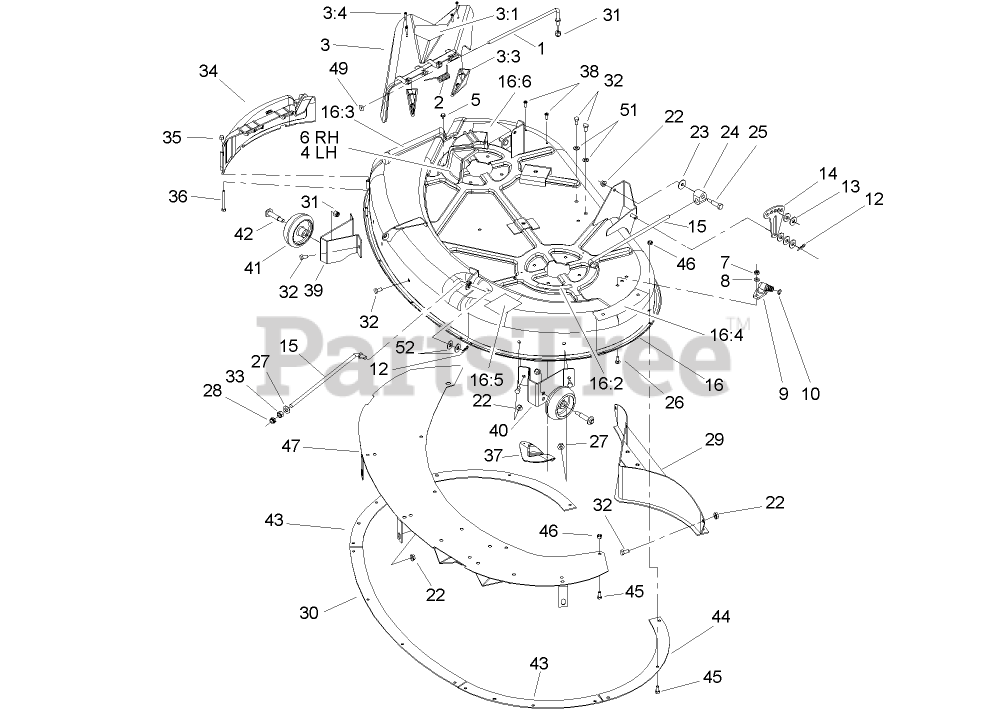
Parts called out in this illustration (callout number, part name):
1	ROD-PIVOT
2	SPRING
3	DEFLECTOR ASM
3:1	DECAL-DANGER
3:3	KICKER
3:4	SCREW-PPH
5	SCREW-HWHTF
6	GUIDE-BELT, RH
7	NUT-LOCK, NI
8	WASHER-FLAT
10	O-RING
12	PIN-HAIR
13	WASHER-HARDENED
14	LINK-ADJUSTING, HOC
15	ROD-HANGER
16:2	DECAL-DANGER, SHIELD
16:3	DECAL-DANGER, DEFLECTOR
16:4	DECAL-DANGER
16:5	DECAL-ROUTING, BELT
16:6	DECAL-DANGER
22	NUT-HF
23	WASHER-PIVOT
24	TRUNNION-HOC
25	SCREW-SHOULDER, HH
26	BOLT-CARR
27	WASHER-FLAT
28	NUT-LOCK, NI
29	REAR BAFFLE ASM
30	RING-BLOW OUT
31	NUT-LOCK, NI
32	SCREW-HH
33	NUT-HEX
34	COVER-DISCHARGE, DECK
35	NUT-CAP
36	SCREW-HH
37	PLATE-KICKER
38	SCREW-PPH
39	BRACKET-GAGE WHEEL, RF
40	BRACKET-GAGE WHEEL, LF
41	WHEEL-GAGE
42	SCREW-SHOULDER, HWH
43	RING-BLOW OUT, SIDE
45	SCREW-HH
46	NUT-LOCK, NI
47	BAFFLE UPPER ASM
49	O-RING
51	WASHER-PLAIN
52	WASHER-FLAT
